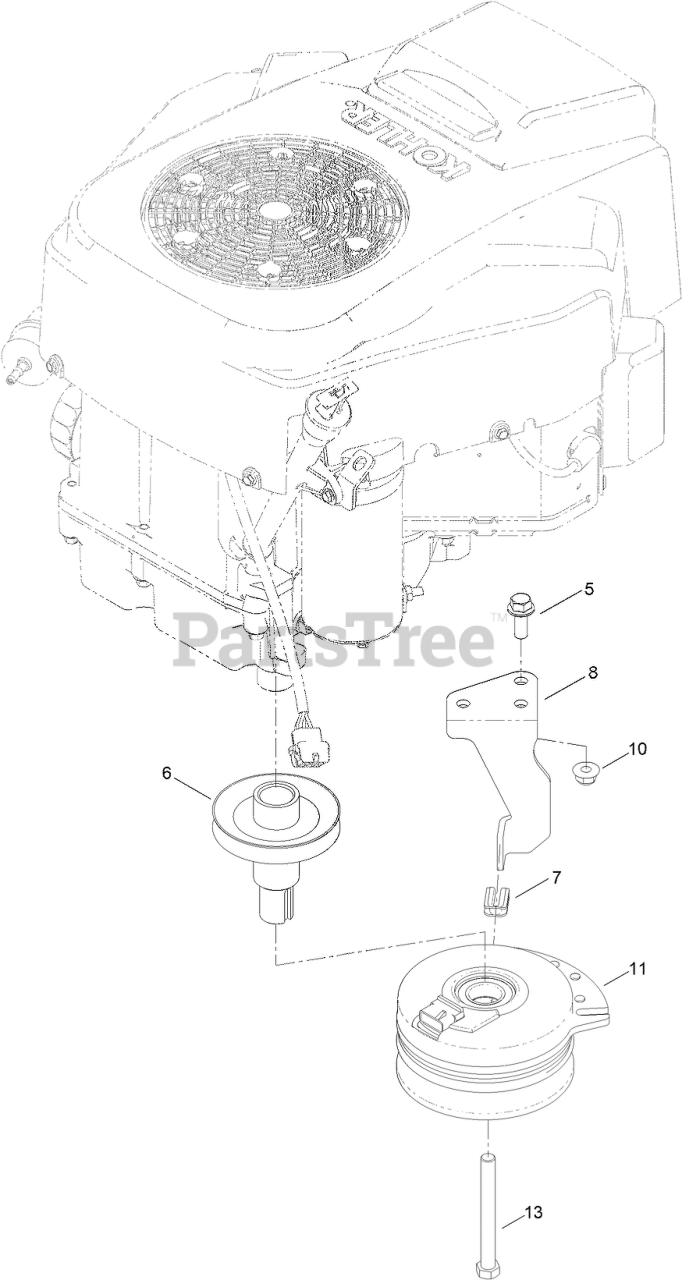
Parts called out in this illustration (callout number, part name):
5	SCREW-HHF
6	PULLEY-ENGINE
7	ISOLATOR-CLUTCH
8	STOP-CLUTCH
10	NUT-HF, NI
11	CLUTCH-ELECTRIC
13	SCREW-HH
